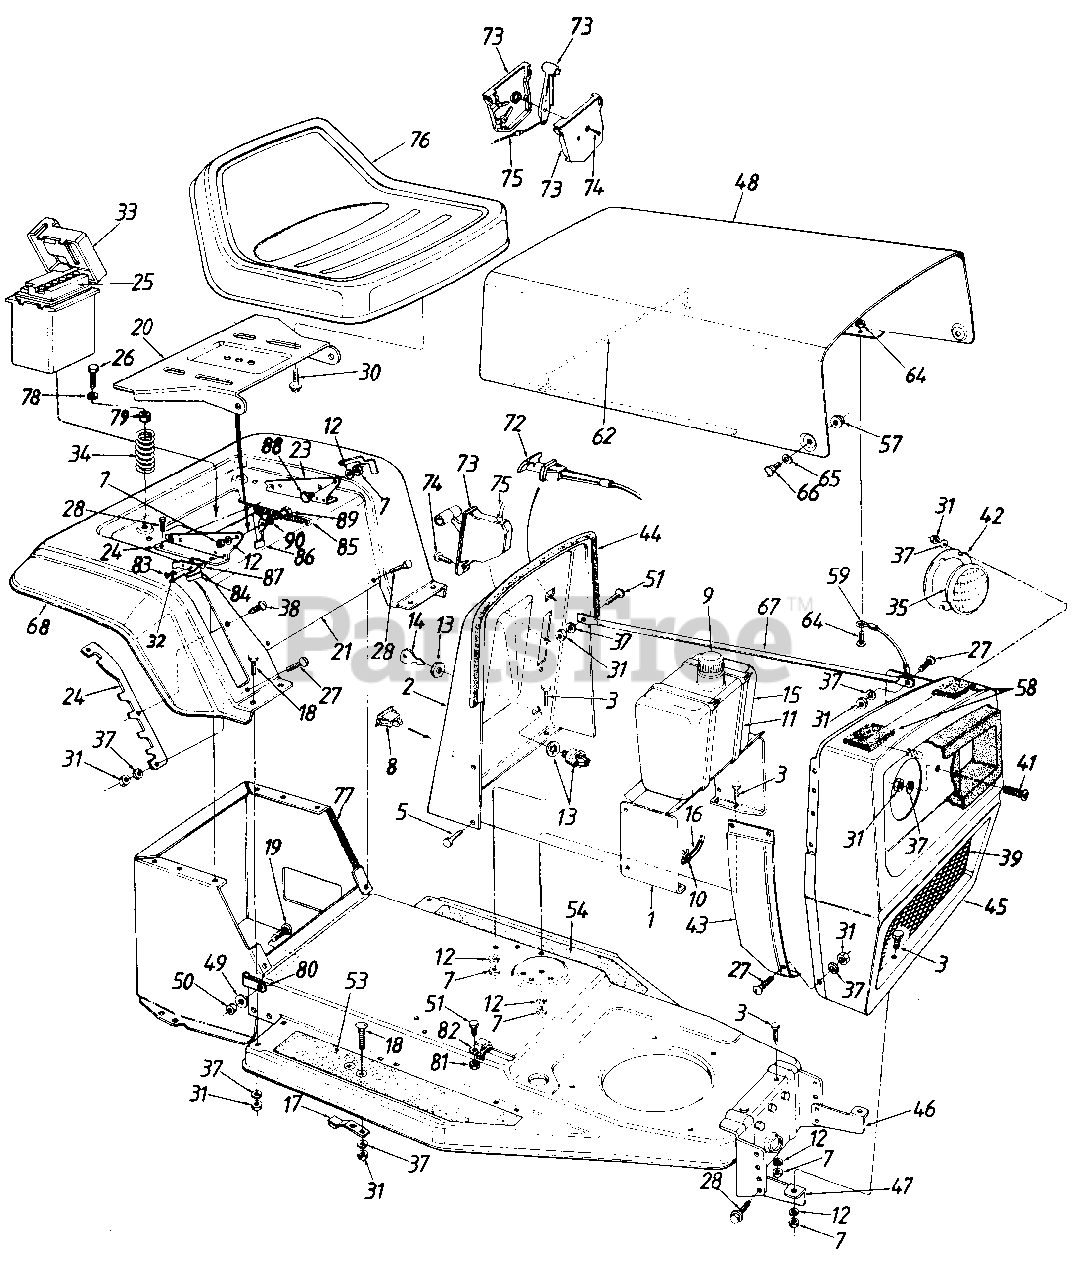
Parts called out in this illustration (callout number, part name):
1	Dash Panel Support Brkt.
5	Hex AB-Tap Scr. 1/4 x .62"
7	Hex Nut 5/16-18 Thd.
8	Light Switch
9	Gas Gauge
11	Cable Tie
12	L-Wash. 5/16" I.D.
13	Ignition Switch
14	Ignition Key
15	Fuel Tank
16	Gas Line
17	Blade Brake Ass'y.
18	Carriage Bolt 1/4-20 x .62"
19	Ribbed Neck Bolt 3/8-24 x .8"
20	Seat Pivot Brkt.
21	Rear Fender
23	Seat Hinge Support Brkt. L.H.
24	Deck Lift Index Brkt.
25	Battery
26	Hex Self-Tap Screw 5/6-18 x 1" Lg.
27	Truss Mach. Scr. 1/4-20 x .75" Lg.
28	Hex AB-Tap Scr. 5/16 x .75" Lg.
30	Hex Self-Tap Scr. 3/8-16 x .75" Lg.
31	Hex Nut 1/4-20 Thd.
32	Fiber Washer
33	Battery Box wlCover
34	Compression Spring
35	Headlight
37	L-Wash. 1/4" I.D.
38	Hex Wash. Hd. Tap Scr. #10 x .5" Lg.
39	Grille Insert
41	C-Sunk Mach. Scr. 1/4-20 x 1 .5"
42	Headlight Retainer
43	Side Panel-R.H.
44	Trim Strip 26 l/2" Lg.
46	Grille Mtg. Brkt.-L.H.
47	Grille Mtg. Brkt.-R.H.
50	Hex L-Nut 3/8-24 Thd.
51	Hex Bolt 1/4-20 x .62" Lg.
53	Foot Pad-R.H.
54	Foot Pad-L.H.
57	Lock Nut 1/4-28 Thd.
58	Foam Strip
64	Hex Sems Nut #10-24 Thd.
65	Spr. Wash. .39" I.D. x .62" O.D.
66	Shld. Bolt
67	Grille Support
68	Trim Strip 79" Lg.
72	Choke Control
73	Throttle Control Box
74	Truss AB-Tap Scr. #10 x .5"
75	Throttle Wire
76	Seat Assembly
77	Trim Strip 5" Lg.
78	Flat Wash. .344" I.D. x .88" O.D.
80	Clamp
81	Hex L-Nut 1/4-20 Thd.
83	Hex Tap Scr. #8 x .5" Lg.
84	Spring Switch
85	Ext. Spring 5.31" Lg.
86	Seat Lift Brkt.
87	Insulator Nut Plate
88	Shld. Bolt.437" Dia. x .162" Lg.
89	Shld. Bolt .437" Dia. x .268"
90	Spr Wash. .445" I.D. x .75" O.D.
